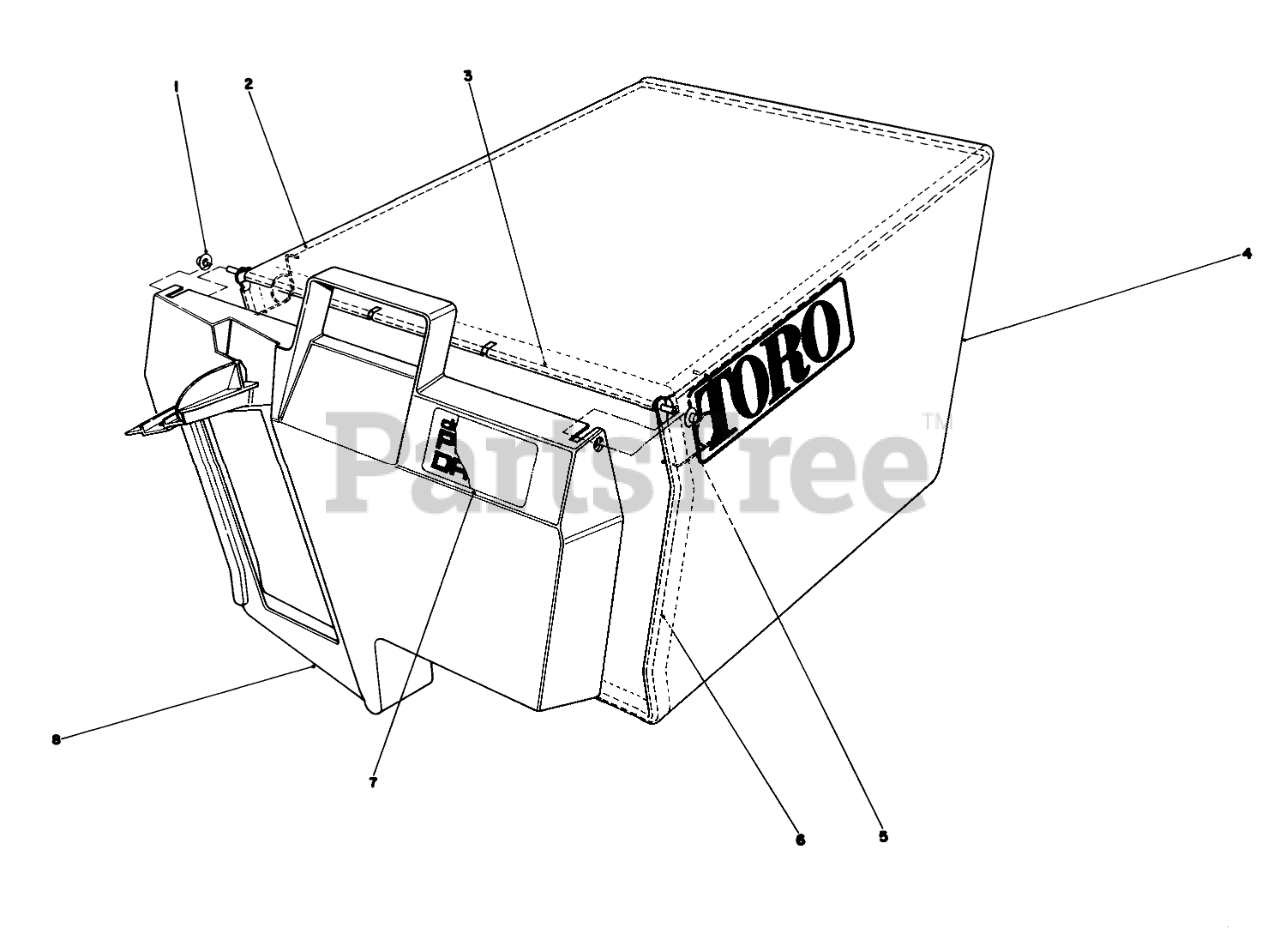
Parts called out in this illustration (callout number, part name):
1	NUT-PUSH
2	FRAME-BAG, UPPER
3	HINGE-DOOR, BAG
4	Bag
5	SPRING
6	FRAME-BAG
7	BAG DOOR DECAL
8	Door Grass Bag
